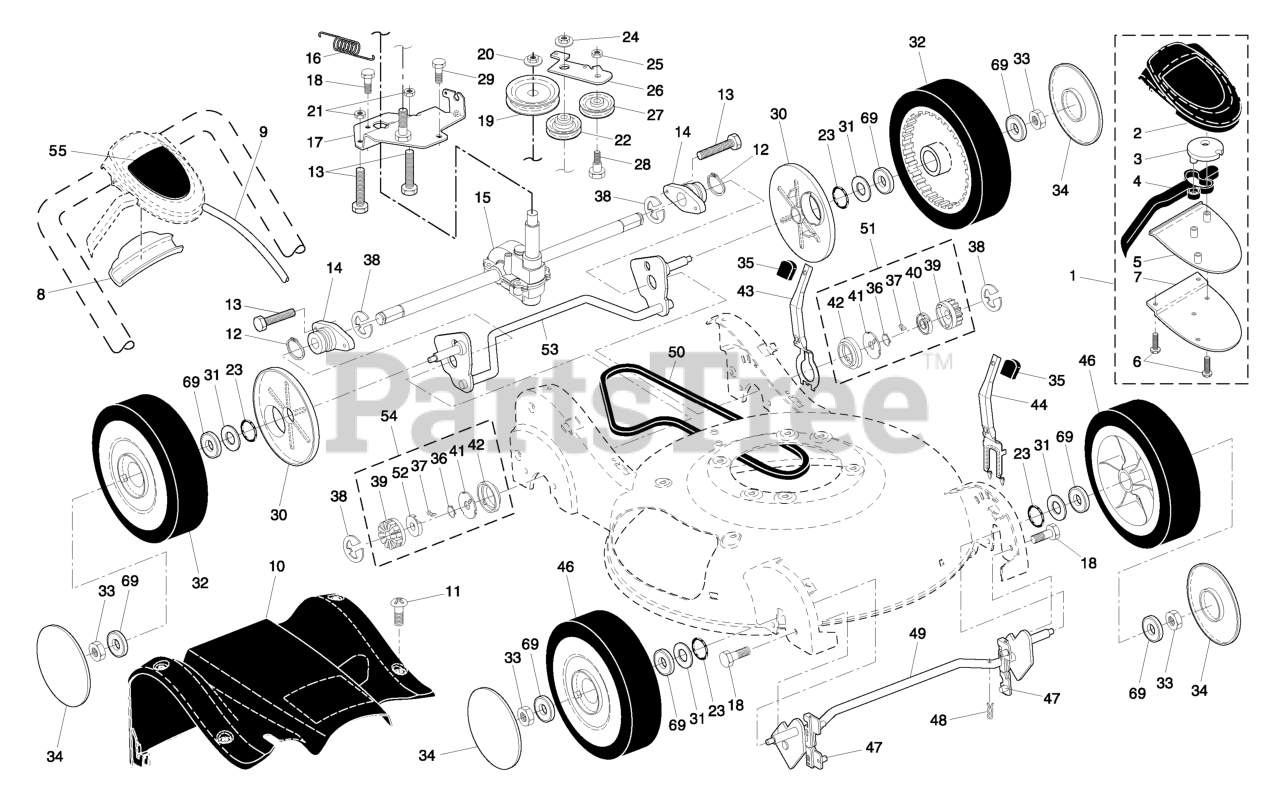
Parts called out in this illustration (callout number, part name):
1	CONTROL DRIVE
2	COVER, DRIVE CONTROL, TOP
3	PULLEY.CAM.DRIVE.CONTROL.HV
4	LEVER
5	COVER, DRIVE CONTROL BOTTOM
6	SCREW, PHILLIPS HEAD 10 X 5/8
7	BRACKET, DRIVE CONTROL
8	EZ WALK SNAP COVER PLATE
9	CABLE, DRIVE CONTROL
10	COVER ASM. DRIVE
11	SCREW
12	RETAINING RING (2 2)(3 2)
13	RP SCREW
14	BEARING.SUPPORT.ASSEM
15	TRANSMISSION.21.HI-VAC.EZ
16	SPRING.RETURN
17	BRACKET TRANSMISSION
19	RP PULLEY DRIVE
20	FLANGED LOCKNUT 3/8-16 ZINC
21	NUT
22	PULLEY.IDLER.V-BELT
23	O-RING
24	NUT
25	NUT.CENTERLOCK.5/16-
26	ARM.IDLER.BZP
27	IDLER PULLEY
28	SHOULDER BOLT
29	SCREW 14-20 X 5/8
30	DUST COVER, WHEEL
31	WASHER.FLAT.1/2
32	WHEEL.9X2.25.PR.JUNG.BLK
33	HEX FLANGE LOCKNT
34	RB HUBCAP.3-SPOKE.SILVER
35	KNOB.SELECTOR.SPRG.H-GRY (2 2)
36	SPRING, TORSION
37	PAWL.DRIVE.21.EZ-WALK
38	E-RING 7/16 RE
39	GEAR, PINION
40	RETAINER.DRIVE.21.EZ-WALK.LT
41	DISC.DRIVE.21.EZ-WALK
42	SEAL.PINION
43	LEVER, SELECTOR, HEIGHT, REAR
44	LEVER, SELECTOR, HEIGHT, FRONT
46	WHEEL.9X2.25.LP.JUNG.BLACK
47	BUSHING.FRONT.TORQUE.SHAFT
48	SPRING RETAINER
49	SHAFT FRONT
50	BELT.DRIVE.EZ.WALK.HI-VAC
51	PINION ASSY, LH
52	RETAINER, DRIVE, RH
53	AXLE.ASM.REAR.TORQUE.BZP
54	PINION ASSY, RH
55	DECAL.DRIVE.CONTROL.HV
69	BEARING.8".WHEEL
